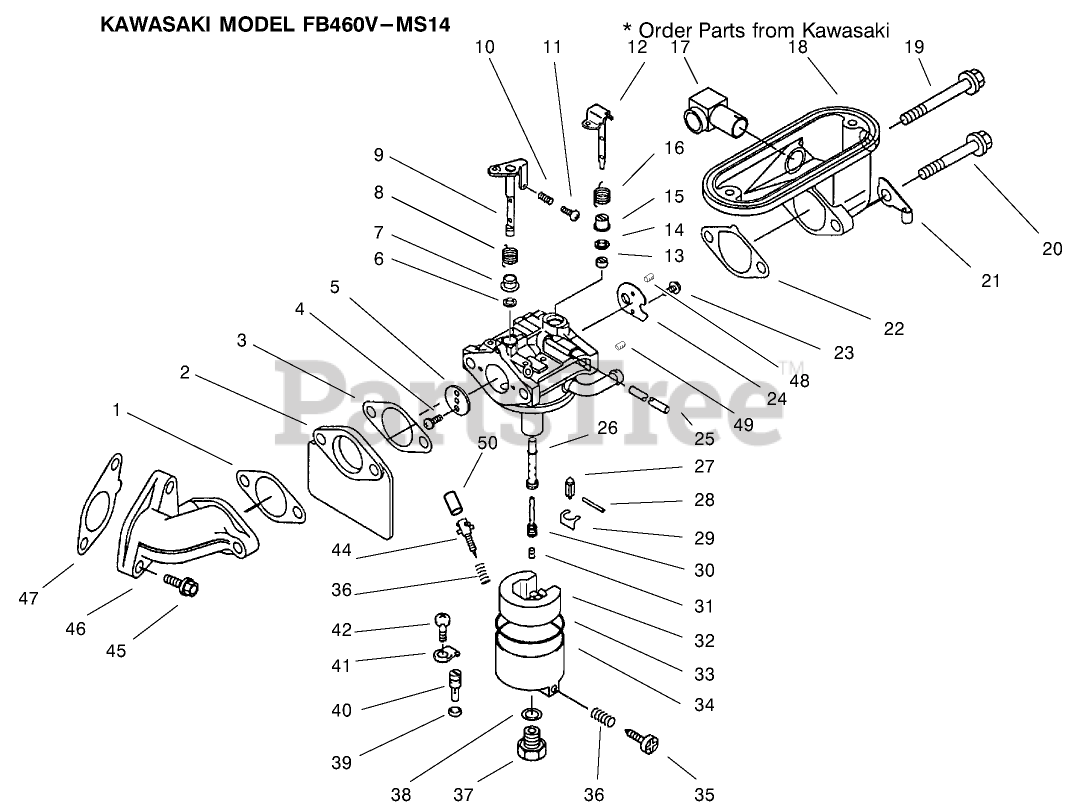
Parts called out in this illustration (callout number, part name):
1	Gasket
3	Gasket-Carburetor
4	Screw
5	Valve-Throttle #110
9	Shaft-Throttle
12	Shaft-Choke
18	Pipe-Intake
22	Gasket
23	Screw
24	Valve-Choke
25	Tube
26	Nozzle-Main
27	Valve-Float
30	Holder-Main Jet
31	Jet-Main
33	Gasket
34	Chamber-Float
35	Screw
38	Gasket
44	Screw-Pilot Air
45	Bolt-Flanged (8X25)
46	Pipe-Intake
47	Gasket-Intake Pipe
48	Jet-Air #0.9
49	Jet-Air #1.4
